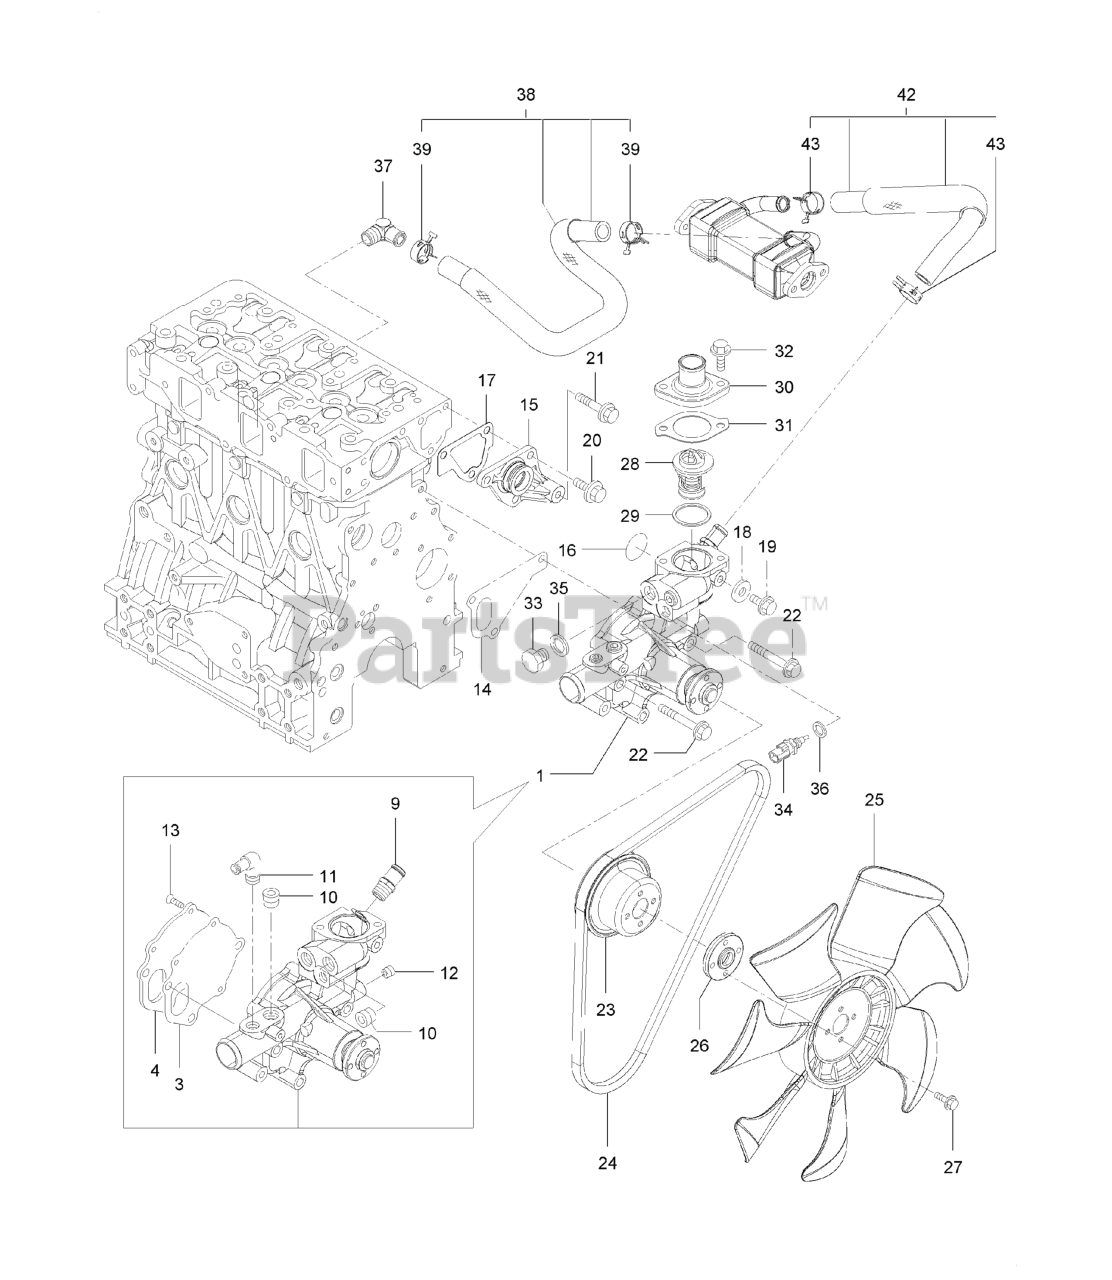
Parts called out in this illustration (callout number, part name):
1	WATER PUMP ASM
20	BOLT
23	V-PULLEY
28	THERMOSTAT
34	SENSOR-THERMOSTAT, CW
36	WASHER-SEAL
38	E G R-C PIPE ASM
39	Clip-Hose
42	CW PIPE ASM
43	Clip-Hose
